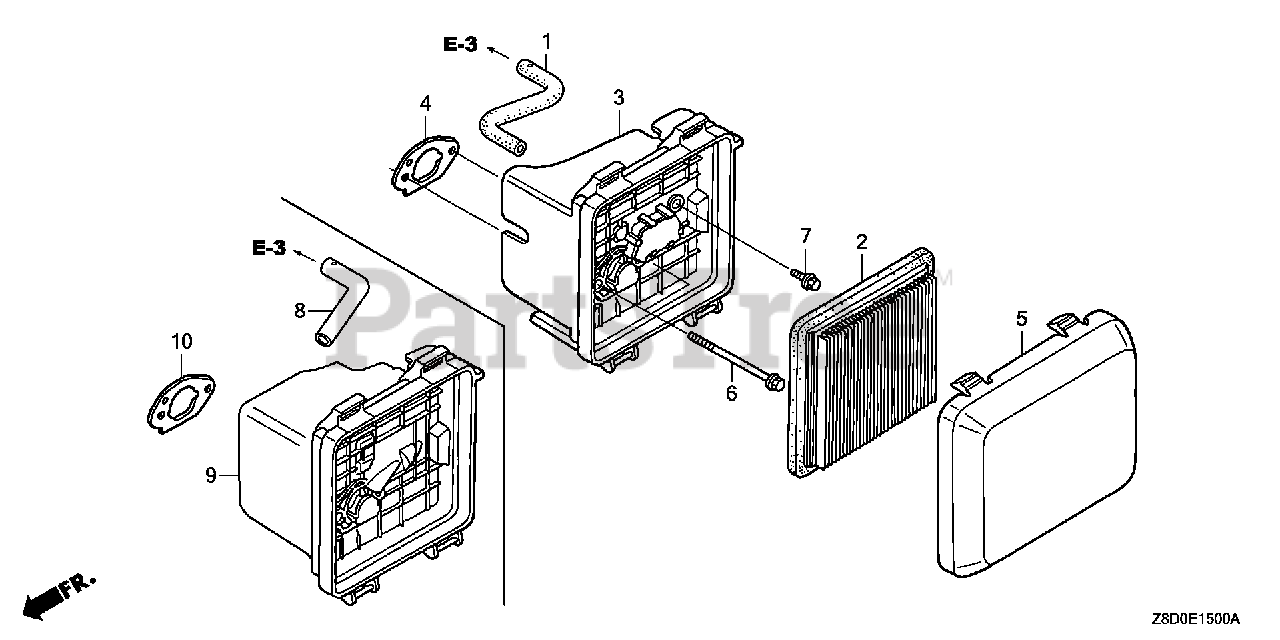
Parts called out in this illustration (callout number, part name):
1	TUBE, BREATHER
2	ELEMENT, AIR CLEANER (TOYO ROKI)
3	CASE ASSY., AIR CLEANER
4	GASKET, AIR CLEANER
5	COVER, AIR CLEANER
6	BOLT, FLANGE (6X86) (CT200)
6	BOLT, FLANGE (6X85) (CT200)
6	BOLT, SPECIAL (6MM)
7	BOLT, FLANGE (6X14)
